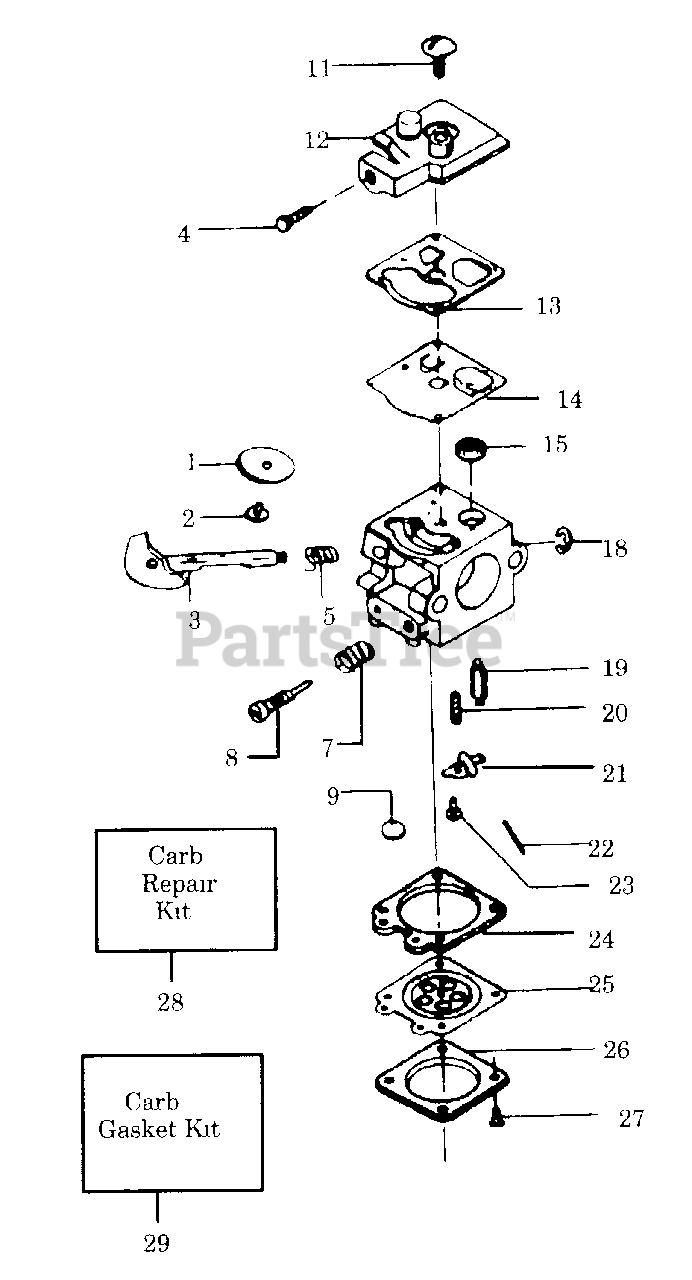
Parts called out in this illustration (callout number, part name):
1	Valve Throttle
2	Screw-Throttle Valve
3	Shaft Ass'y.-Throttle
4	Idle Speed Screw
5	Spring-Throttle Return
7	Spring-High Speed Mixture Needle
8	Needle-High Speed Mixture
9	Plug-5/16 Dia. Welch
11	Screw-Pump Cover
12	Cover-Fuel Pump
13	Gasket-Fuel Pump
14	Diaphragm-Fuel Pump
15	Screen-Fuel Inlet
18	Ring-Throttle Retainer
19	Valve-Inlet Needle
20	Spring-Metering Lever
21	Lever-Metering
22	Pin-Metering Lever
23	Screw-Metering Lever Pin
24	Gasket-Metering Diaphragm
25	Diaphragm-Metering
26	Cover-Metering Diaphragm
27	Screw Ass'y.-Metering Cover
28	Kit-Carb. Kwik Repair (Inc. 13,14,24,25)
29	Kit-Carb. Gasket/Diaphragm (Inc. 9,13,14, 19,20,21,22,23,24,25)
